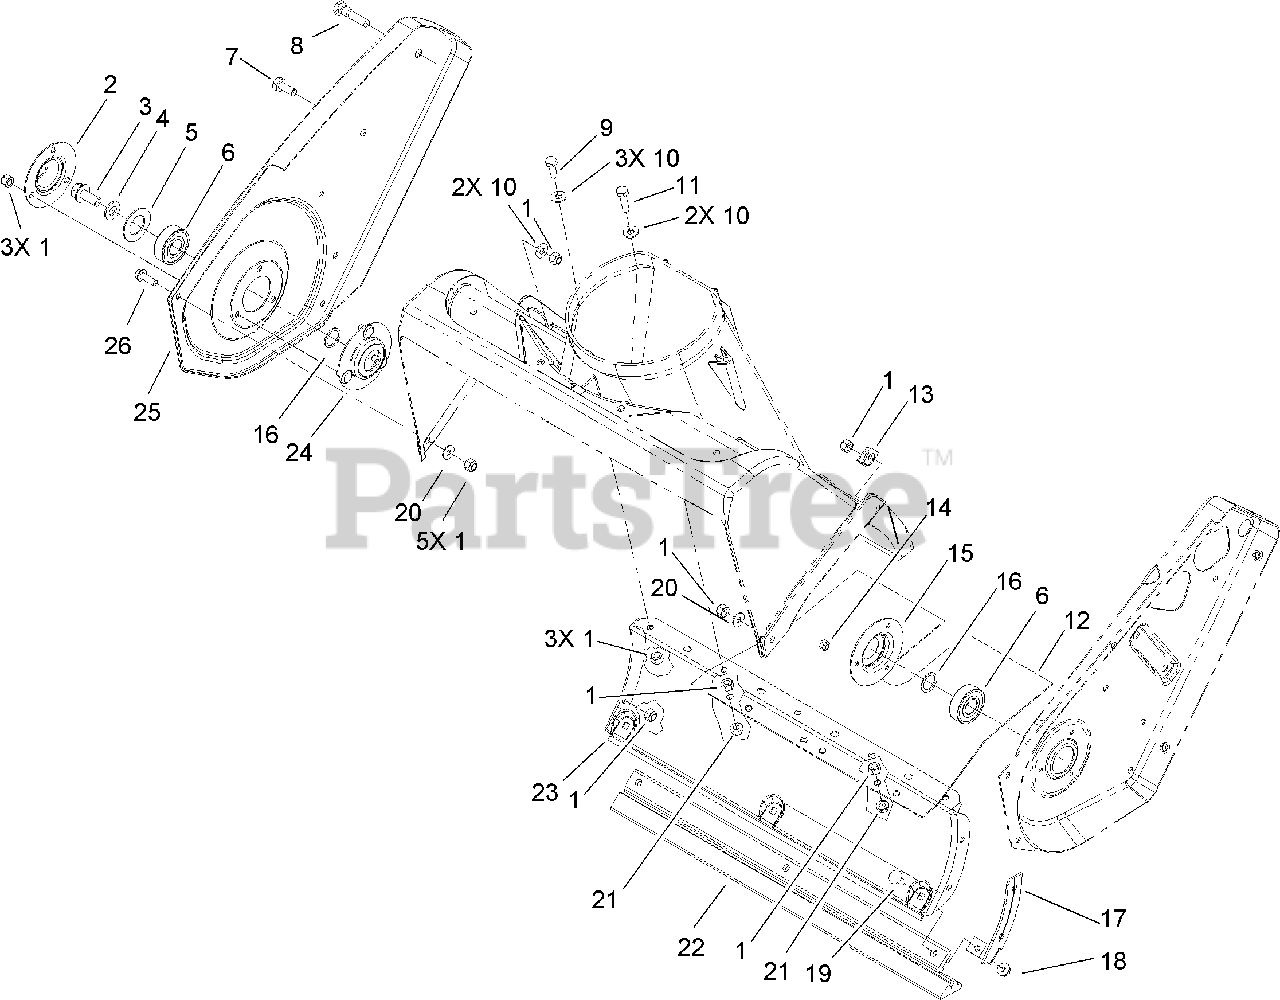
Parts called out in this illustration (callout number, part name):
1	NUT-LOCK, NI
2	RETAINER-BEARING
3	SCREW-HHF
4	WASHER-FLAT
5	WASHER-RUBBER
6	BEARING-BALL
7	SCREW-HH
8	PIN-ROTOR
9	SCREW-HH
10	WASHER-FLAT
11	SCREW-HH
12	COVER-BOTTOM
13	BRACKET-HOUSING
14	NUT-LOCK
15	FLANGE-BEARING
16	WASHER-THRUST
17	BRACKET-HOUSING, LOWER
18	NUT-KEPS
19	SCREW-CARR
20	WASHER-FLAT
21	NUT-LOCK, HHF
23	HOUSING-LOWER
24	FLANGE-BEARING
25	SIDEPLATE-RIGHT
